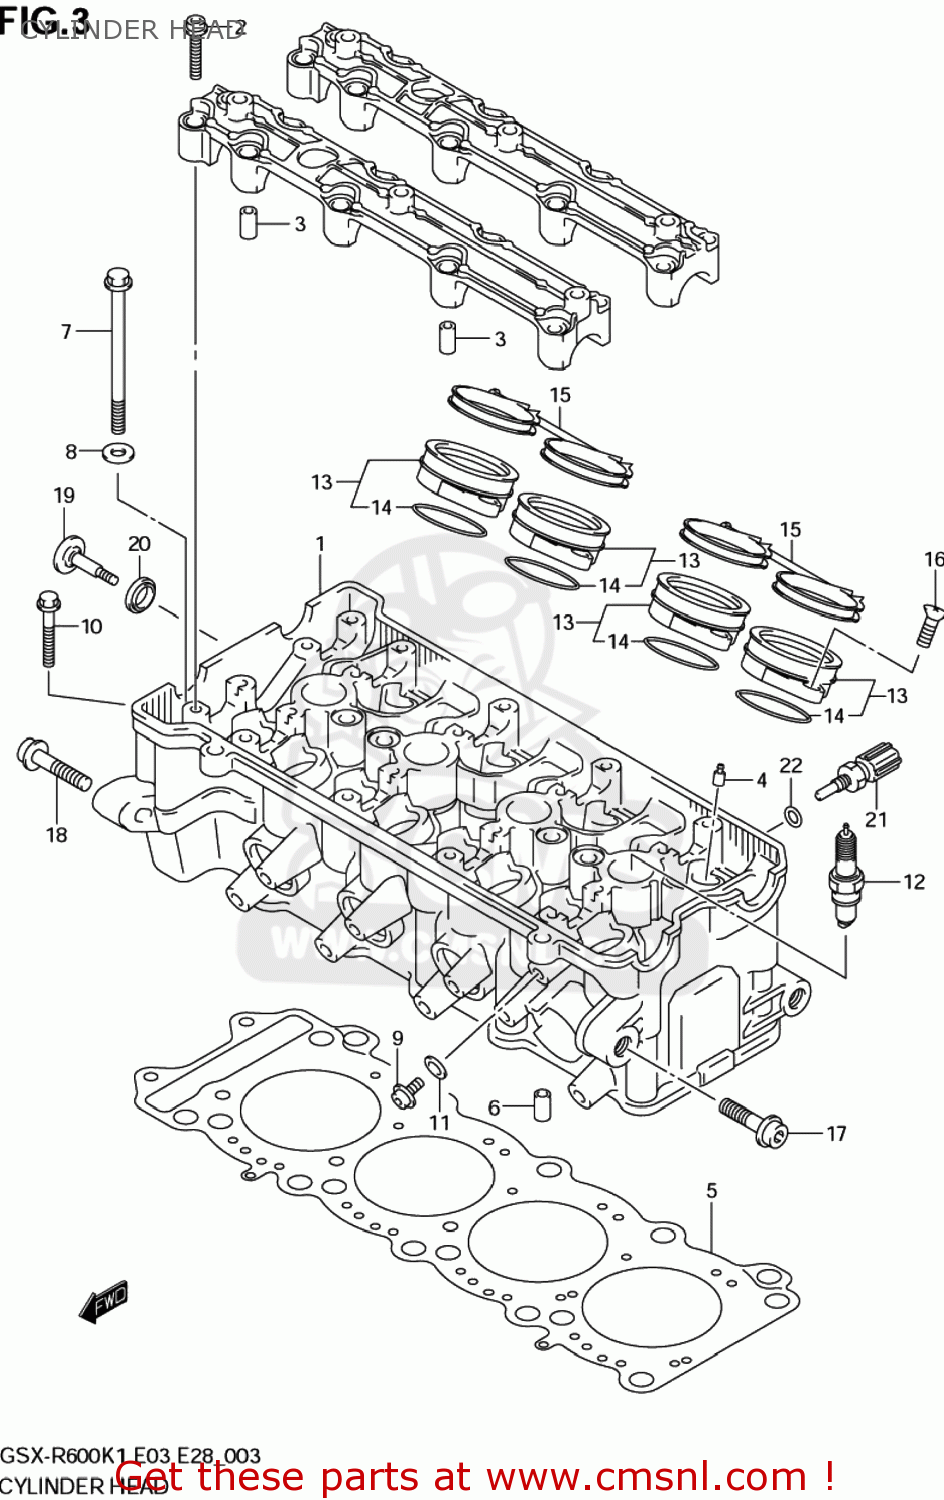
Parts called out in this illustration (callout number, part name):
1	HEAD ASSY,CYLINDER
2	BOLT
3	PIN(6.2X8X16)
4	GUIDE,VALVE
5	GASKET,CYLINDER HEAD (NAS)
6	PIN
7	BOLT(10X95)
8	WASHER(10.5X19X2)
9	BOLT
10	BOLT,CYL.OIL P
11	GASKET(5.8X13X1.2) (NAS)
12	PLUG,SPARK(CR8E)
13	PIPE ASSY,INTAKE
14	O RING(D:2.4,ID:41.7)
15	CLAMP,INTAKE PIPE
16	SCREW ,6X16
17	BOLT(10X45)
18	BOLT(10X55)
19	BOLT,CYL HEAD SIDE FACE
20	WASHER,HEAD COVER
21	SENSOR,WATER TEMP
22	GASKET(12X17X1) (NAS)
